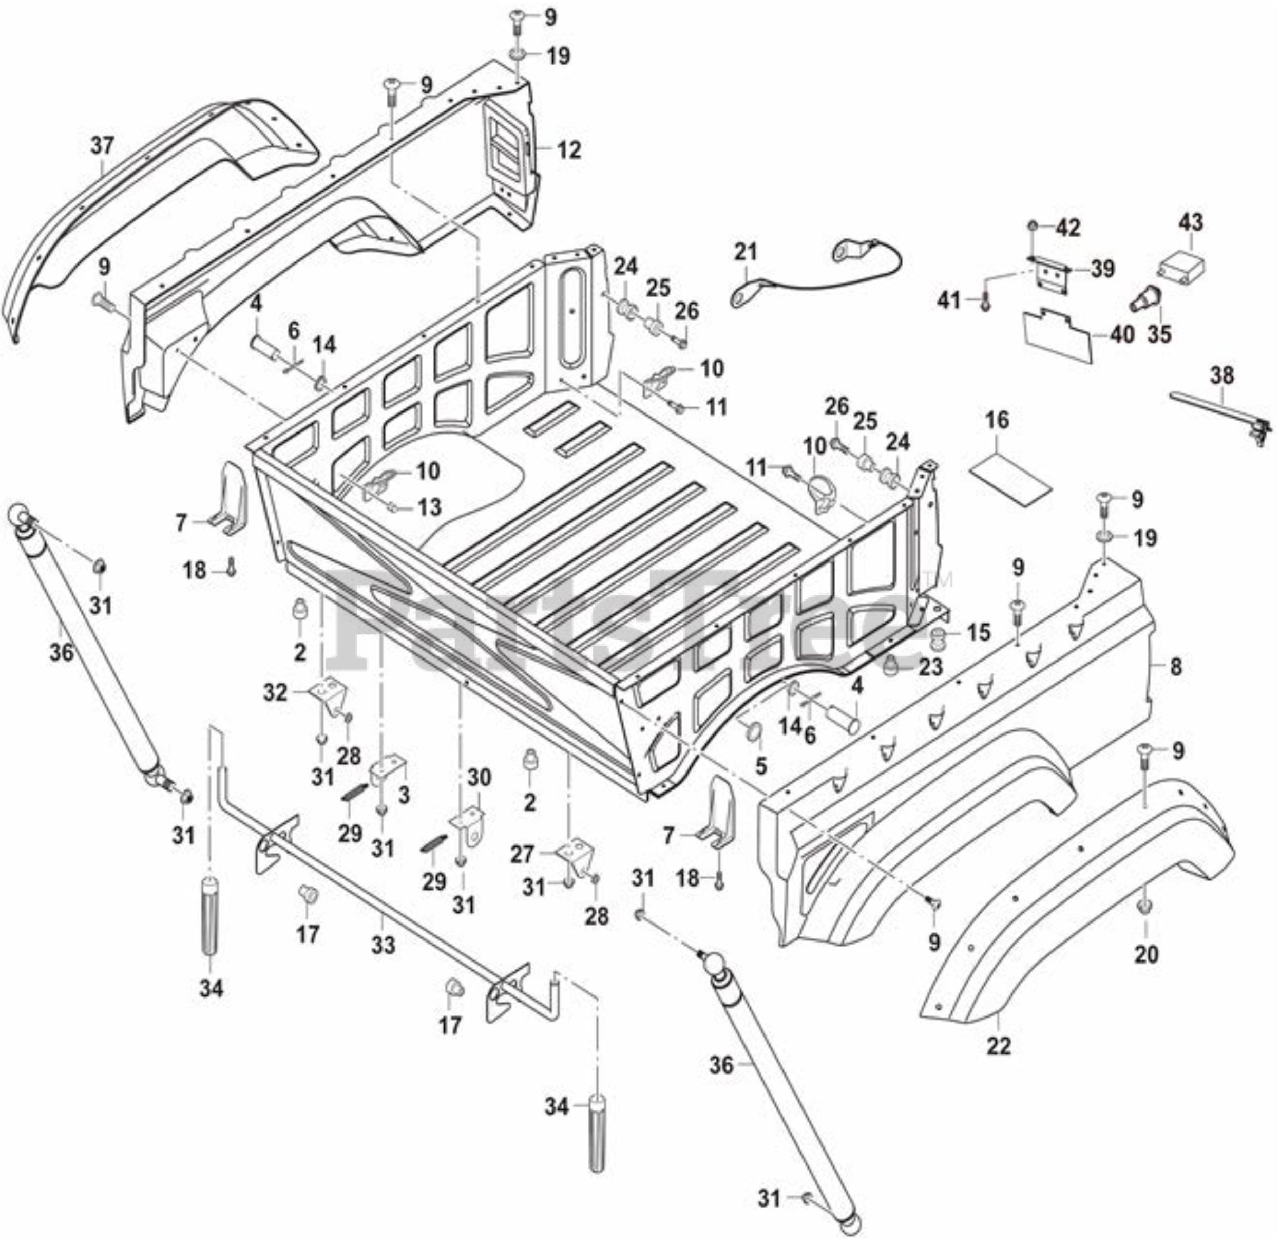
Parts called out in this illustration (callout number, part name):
1	Rear Cargo Bed
2	Spiral Cushion Gasket
3	Mounting Plate III, Turnup Bracket
4	Bed Spiale 12X62
5	Flat Rubber Gasket 12X25X5.5
7	Backplate, Turnup Bracket
8	Rear Left Board-Red
8	Rear Left Board-Blue
8	Rear Left Board-MTD Yellow
8	Rear Left Board-G2 Camo
9	Cross Large Plate Head Screw M6X16
10	Strip Hook
11	Cross Large Plate Head Screw M6X12
12	Rear Right Board-Red
12	Rear Right Board-Blue
12	Rear Right Board-MTD Yellow
12	Rear Right Board-G2 Camo
13	Cap Nut M6X17
14	Flat Gasket 12X24
15	Shock pad,card slot 10X2.5
16	Buffering Rubber Sheet, Cargo Bed
17	Turnup Plastic Liner 14X17X20X10
18	Cross Small Plate Head Tapping Screw ST4.8X13
19	Flat washer 6
20	Hexagon Flange Self-Lock Nuts (With Metallic Insert) M6
21	Dragline Assy C, Cargo Bed Door
22	Left fender rear cover I
23	Shock Pad,circular plug 10X27
24	Shock pad,card slot 10X5
25	Turnup Liner 6.3X10X17
26	Hexagon Flange Bolt M6X30
27	Mounting Plate I, Turnup Bracket
28	Shock pad,card slot 14X2.5
29	Tension Spring 2X14X40
30	Mounting Plate II, Turnup Bracket
31	Hexagon Flange Bolt M8
32	Mounting Plate IV, Turnup Bracket
33	Cargo Anti-Roll Lever
34	Handle Rubber Sleeve
35	Position lights bulb ?12V?W5W
36	Bed Gas Spring Combinations
37	Right fender, rear cover I
39	Licence Plate mounting plate
40	Licence Plate mounting plate II
41	Flange Bolt M6X16
42	Flange Nut M6
43	Licence Plate lights
